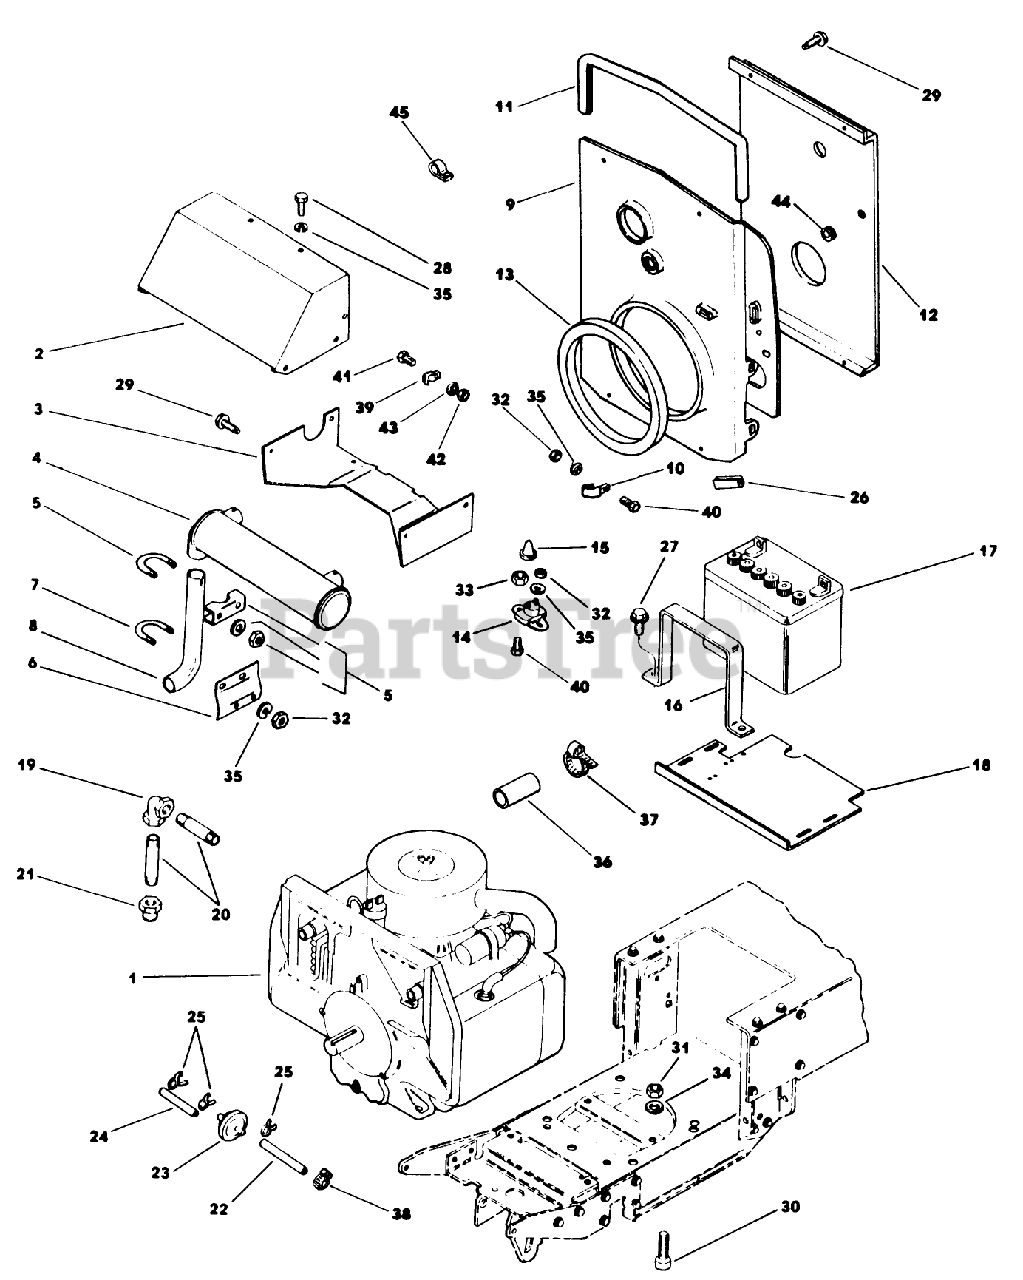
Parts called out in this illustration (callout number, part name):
6	Stack-Carburetor
16	Battery Strap Decal Assembly
19	3/8" Street Elbow
30	Cap Screw, Hex Socket Hd. 3/8-16 x 1-1/4 Plated, Grade 5
43	Lock Washer 5/16 Plated
